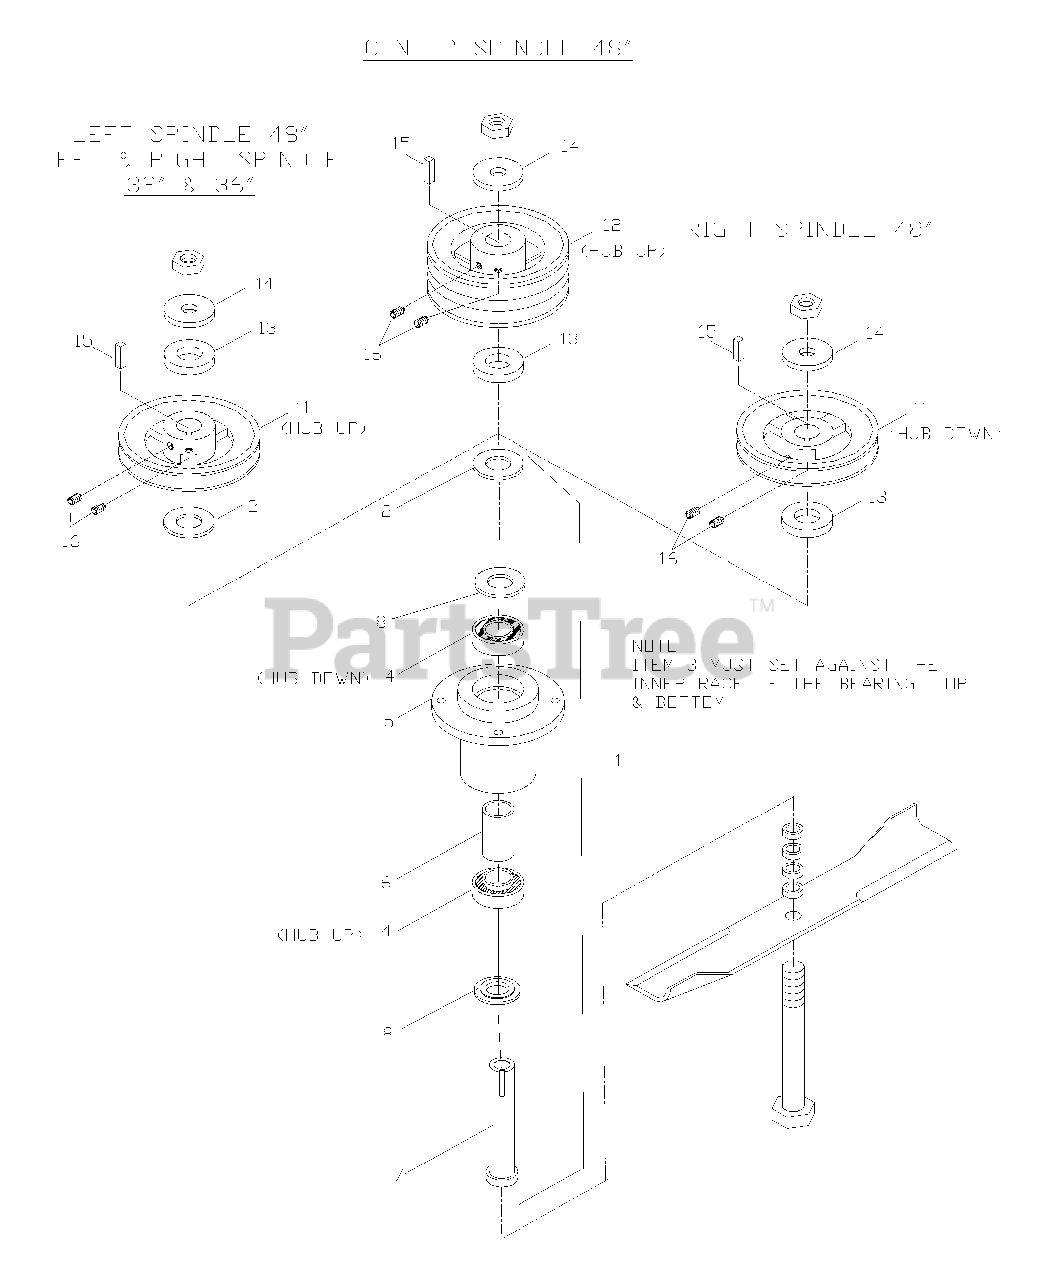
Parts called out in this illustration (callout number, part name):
1	CUTTER HOUSING ASM.
2	MACH.BUSING 10GA.
4	BEARING
8	COMBO SPACER
12	DOUBLE PULLEY
13	3/8 SPACER
14	1/4 SPACER
15	KEY 1/4 SQ. X 1 1/8
16	5/16 NYLOC SETSCREW
